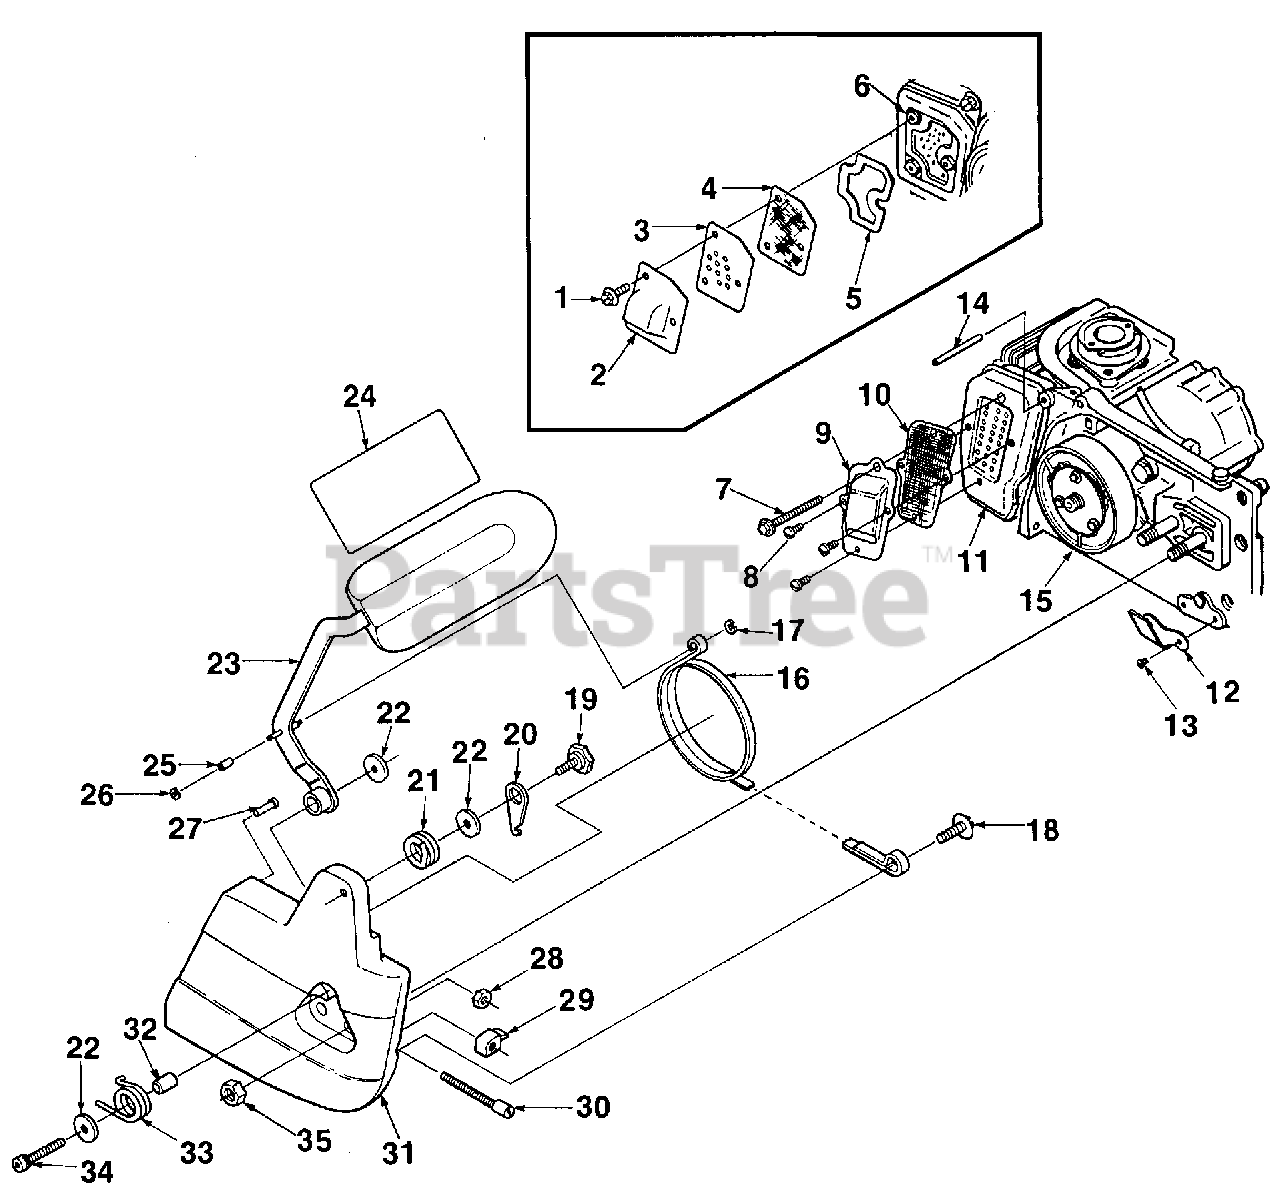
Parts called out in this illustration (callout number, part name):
1	SCREW- Hex sems, 8-32 x 3/8 (prior to lot #C-320)
2	PLATE- Muffler exhaust (prior to lot #C-320)
3	BAFFLE (prior to lot#C-320)
4	ARRESTOR- Spark (accessory) prior to lot #C-320)
5	GASKET- Exhaust plate (prior to lot #C-320)
6	MUFFLER (prior to lot #C-320)
7	SCREW (After lot #C-320)
8	SCREW (After lot #C-320)
9	PLATE- Exhaust (After lot #C-320
10	SCREEN- Spark arrestor (Opt.) (After lot #C-320)
11	MUFFLER (After lot #C-320)
12	STOP- Chain
13	SCREW- Hex hd. sems 8-32 x 1/2
14	PIN- Dowel (125 x 1 3/8)
15	DRUM & HUB
16	BRAKEBAND
17	"E" RING
18	SCREW- Pan hd. 1/4-20 x 5/8
19	SCREW- Shoulder
20	LEVER- Locking
21	SPRING- Locking lever
22	WASHER
23	LEVER- Brake w/guard
25	BEARING- Roller
26	"E" RING
27	SLEEVE- Headed
28	NUT- Centerlock
29	PIN- Guide bar adjusting
30	SCREW- Guide bar adjusting
31	COVER- Drivecase
32	SLEEVE- Lever
33	SPRING- Brake lever
34	SCREW- Soc cap hd.
35	NUT- Hex 5/16-18
